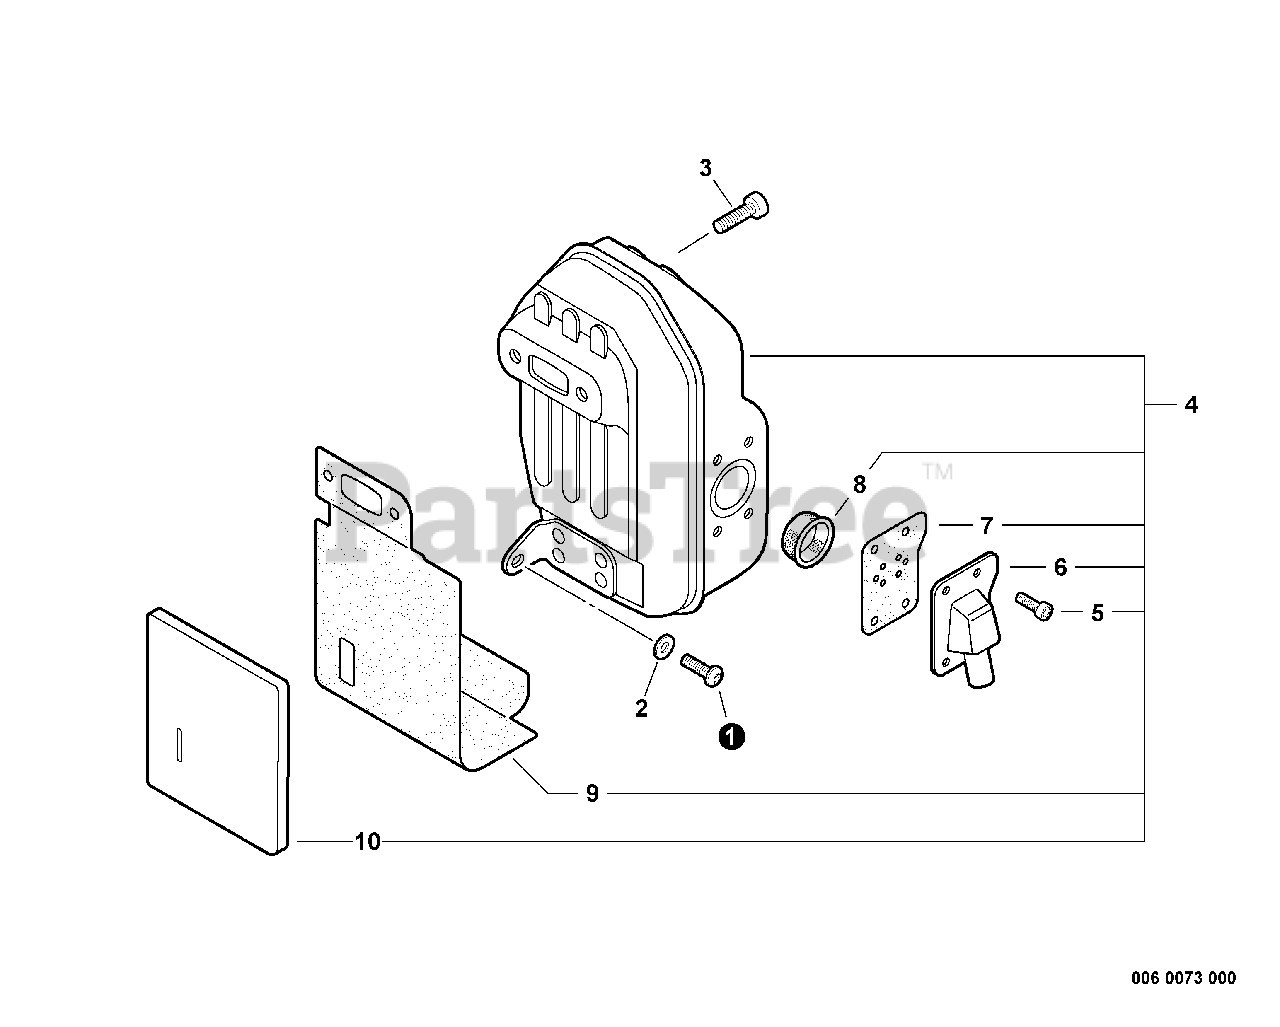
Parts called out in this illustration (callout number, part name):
1	BOLT, TORX 5×16
2	WASHER 5.5×16×2T
3	BOLT, TORX 6×20
4	MUFFLER ASSY
5	BOLT, TORX 4×8
6	GUIDE, EXHAUST
7	GASKET, EXHAUST
8	SCREEN, SPARK ARRESTER
9	HEAT SHIELD, EXHAUST
10	INSULATOR, MUFFLER
